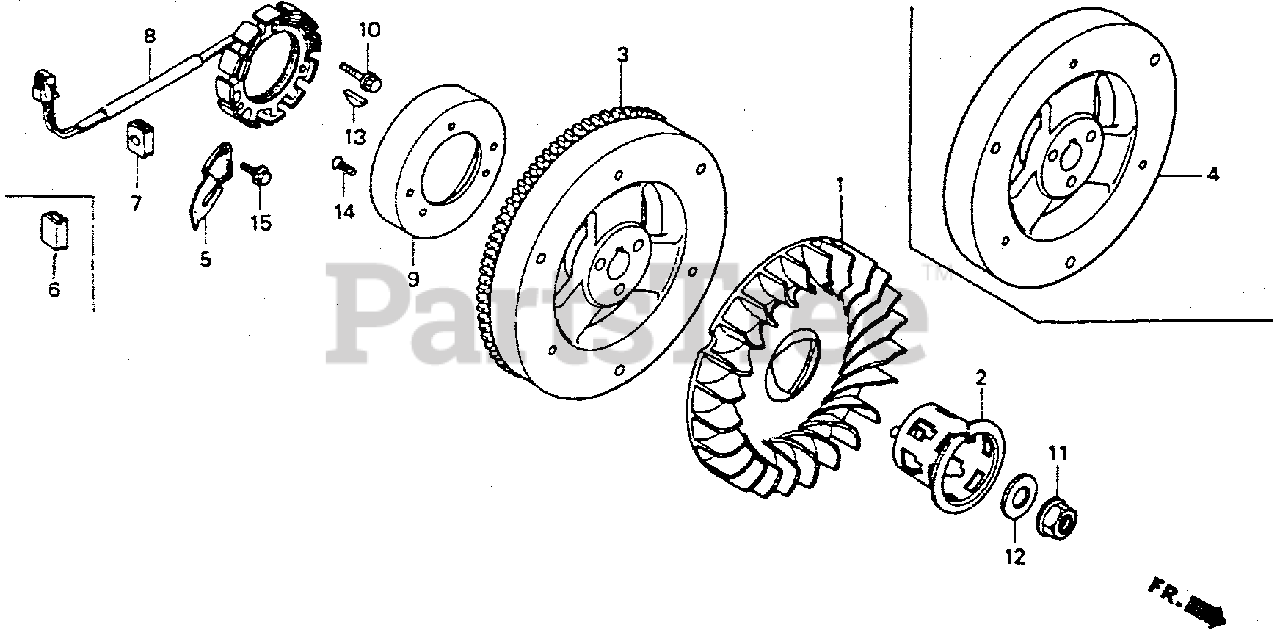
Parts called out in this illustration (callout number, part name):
1	FAN, COOLING
2	PULLEY, STARTER
4	FLYWHEEL (USA)
6	GROMMET, WIRE
11	NUT, FLANGE (20MM)
12	WASHER (20MM)
13	KEY, WOODRUFF (50X7)
